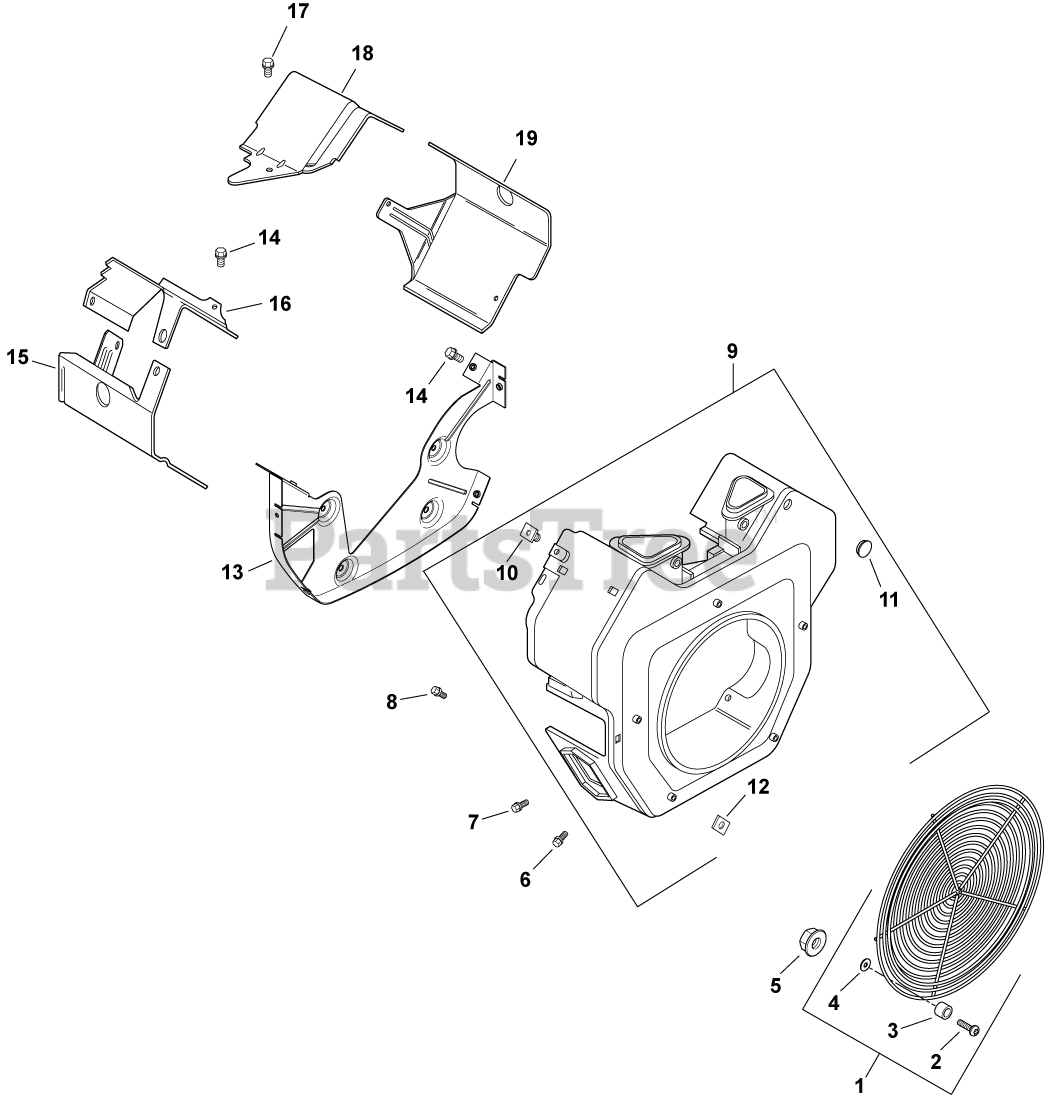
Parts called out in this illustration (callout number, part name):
1	KIT, GRASS SCREEN GUARD
2	SCREW, SPECIAL HEAD
4	WASHER, FLAT 1/4" (O.D. 5/8")
6	SCREW - USE M-545016-S
7	SCREW,FLG THD FRM M5X0.8X16-(#25086398S)
8	SCREW, FLG THD FRM M5X.8X20-(#25086399S)
9	KIT, BLOWER HOUSING ASSEMBLY USE 24 027 477-S
10	NUT, PLASTIC (KM)-USE 25 100 37-S
11	PLUG, BUTTON 9/16
12	NUT, PLASTIC
13	PLATE, BACKING-USE 24 146 59-S
14	SCREW,FLG THD FRM M6X1.0X16-(#25086397S)
15	BAFFLE, LEFT BARREL -USE 24 063 88-S
16	BAFFLE, VALLEY #2 SIDE-USE 24 063 94-S
17	SCREW, FLG THD FRM M5X.8X10
18	BAFFLE, VALLEY (CH)-USE 24 063 93-S
19	BAFFLE, RIGHT BARREL-USE 24 063 85-S
